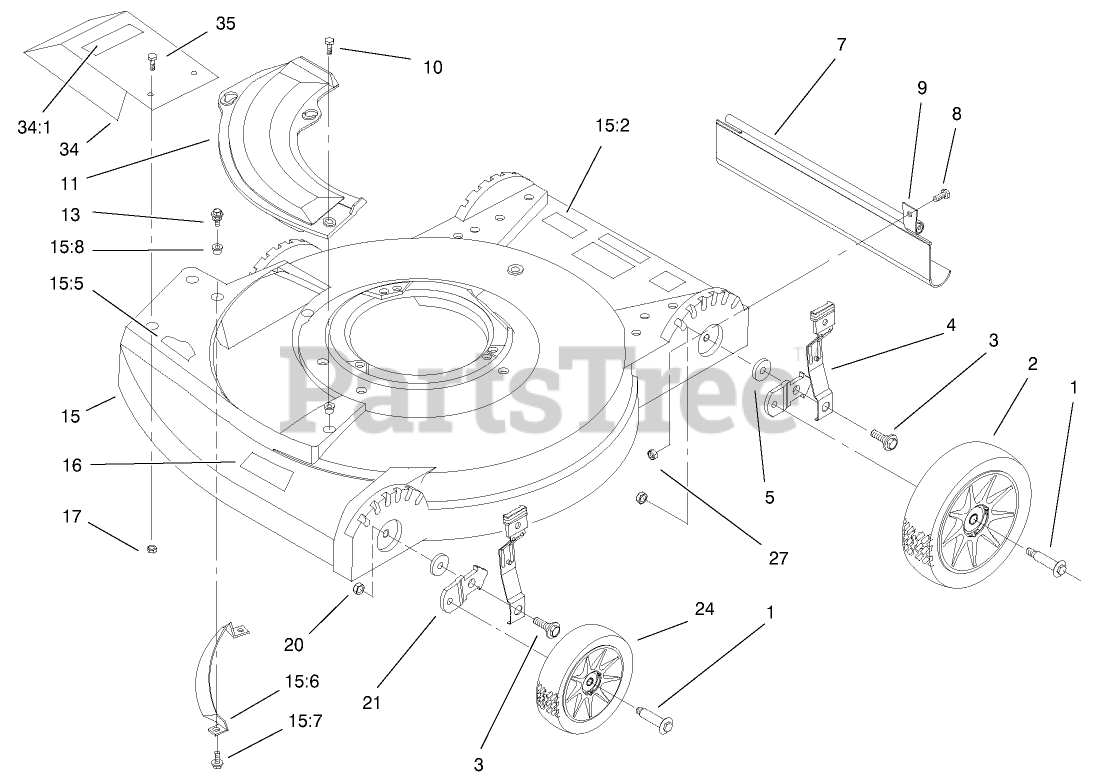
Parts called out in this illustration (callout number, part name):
2	WHEEL/TIRE ASM
4	SPRING ARM ASM
5	WASHER
7	SHIELD-TRAILING
8	SCREW-HH
9	CLAMP-SHIELD
10	SCREW-HWHTF
11	PLATE-OPENING, CHUTE
13	SCREW-SEMS
15	HOUSING ASM
15:2	DECAL-DANGER
15:5	DECAL-DANGER
15:6	BAR-TOE
15:7	SCREW-HWH
15:8	NUT-CLIP
16	DECAL-DECK, HP
17	NUT-LOCK, NI
20	NUT-LOCK, NI
21	BRACKET-HEIGHT, WHEEL
24	WHEEL AND TIRE ASM
27	NUT-LOCK, NI
34	GUARDPLATE (SERVICE)
34:1	DECAL-DANGER
35	SCREW-HWH
